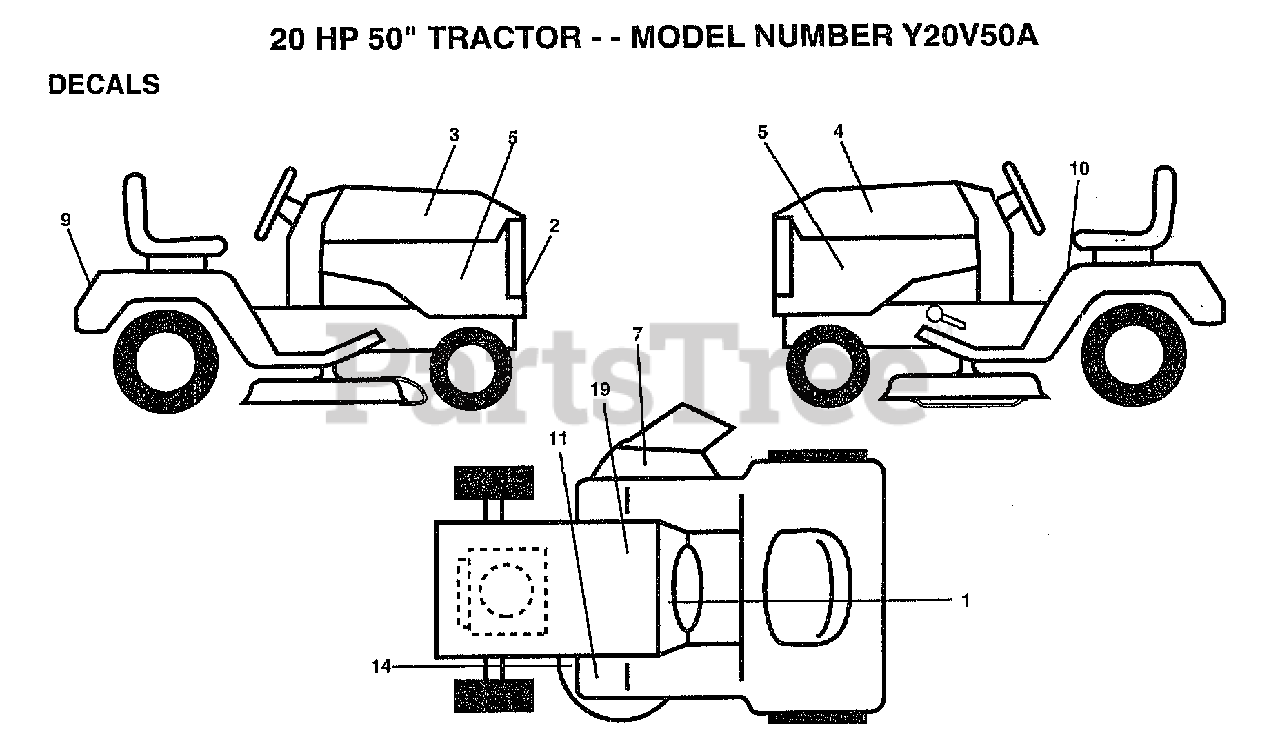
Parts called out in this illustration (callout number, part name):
1	DECAL.DASH.INSTR.
2	DECAL.GRILL.YARDP
4	DECAL HOOD LH
5	DECAL.PNL.SIDE.20
7	"DECAL, WARNING"
10	DECAL CAUTION
11	DECAL T
14	"DECAL.V.BELT.44"""
19	DECAL
